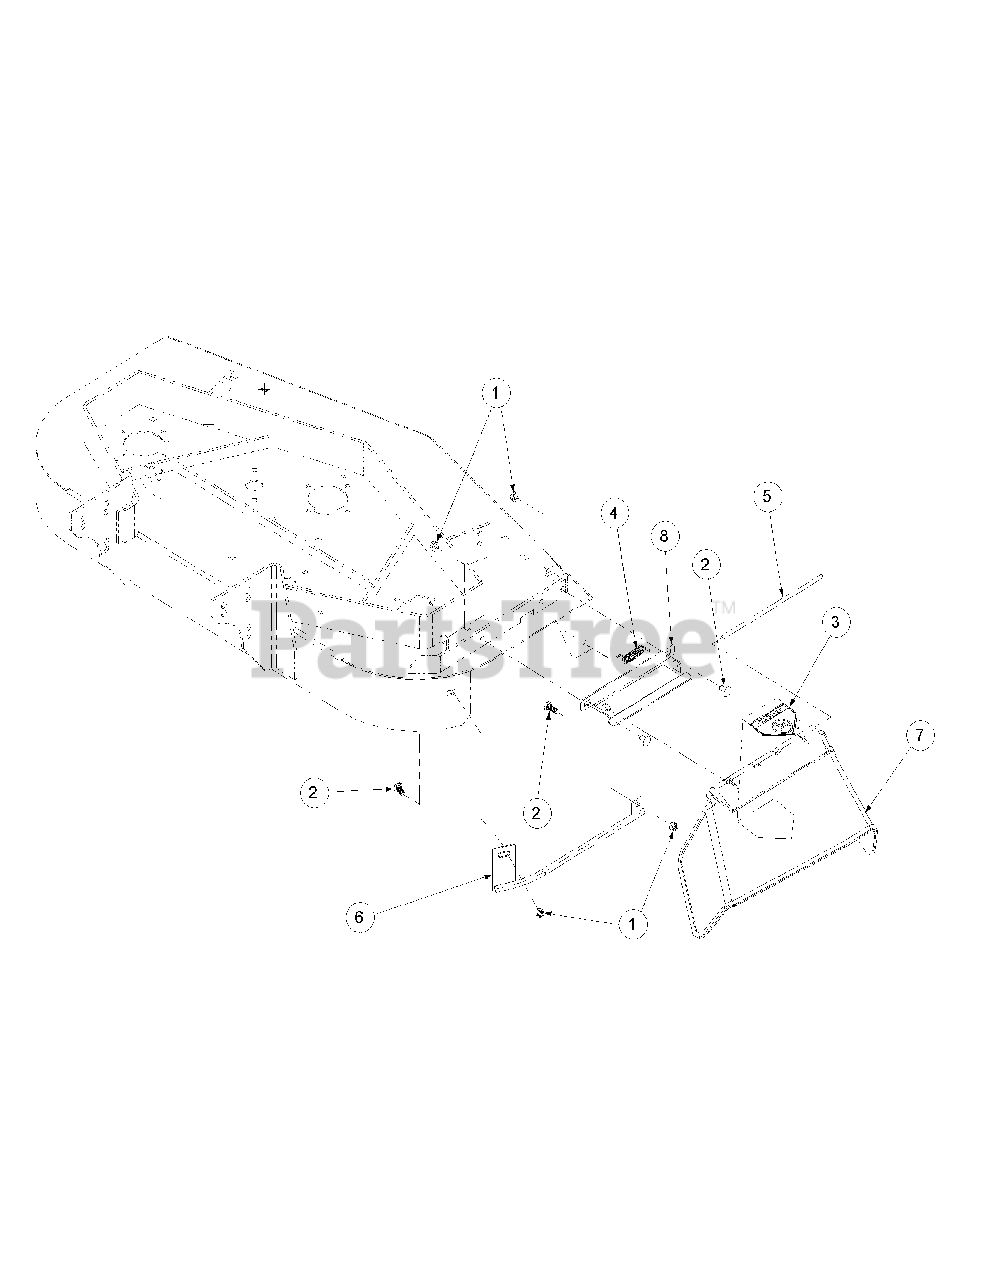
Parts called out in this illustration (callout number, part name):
1	Hex Nut Flange Lock, 3/8-16
2	Carriage Bolt, 3/8-16 x .75 LG.
3	Decal, Danger Hands & Feet
4	Torsion Spring, 0.4 ID x 2.16 LG
5	Chute Deflector Rod
6	Stiffner Assembly, 48
7	Deflector Chute
8	Deflector Chute Bracket
